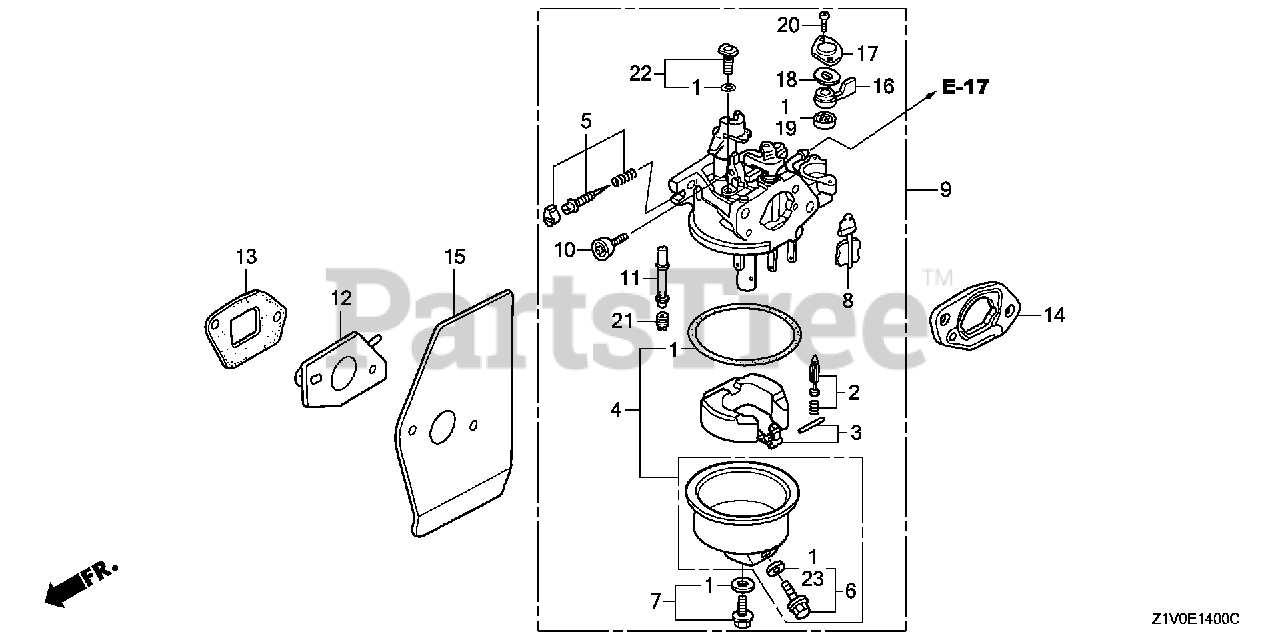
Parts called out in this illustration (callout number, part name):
1	GASKET SET
2	VALVE SET, FLOAT (SEAT NOT INCLUDED)
3	FLOAT SET (CARBURETOR NO.)
4	CHAMBER SET, FLOAT
5	SCREW SET, PILOT
6	SCREW SET, DRAIN
7	SCREW SET
8	CHOKE SET (CARBURETOR NO.)
9	CARBURETOR ASSY. (BE66J A)
10	SCREW, THROTTLE STOP
11	NOZZLE, MAIN (CARBURETOR NO.)
12	INSULATOR, CARBURETOR
13	GASKET, INSULATOR
14	SPACER, CARBURETOR
15	GASKET, CARBURETOR
16	LEVER, PETCOCK
17	PLATE, LEVER SETTING
18	SPRING, PETCOCK LEVER
19	GASKET, PETCOCK
20	SCREW, PAN (3X6)
21	JET, MAIN (#60)
21	JET, MAIN (#62)
21	JET, MAIN (#65)
22	JET SET, PILOT (#35)
